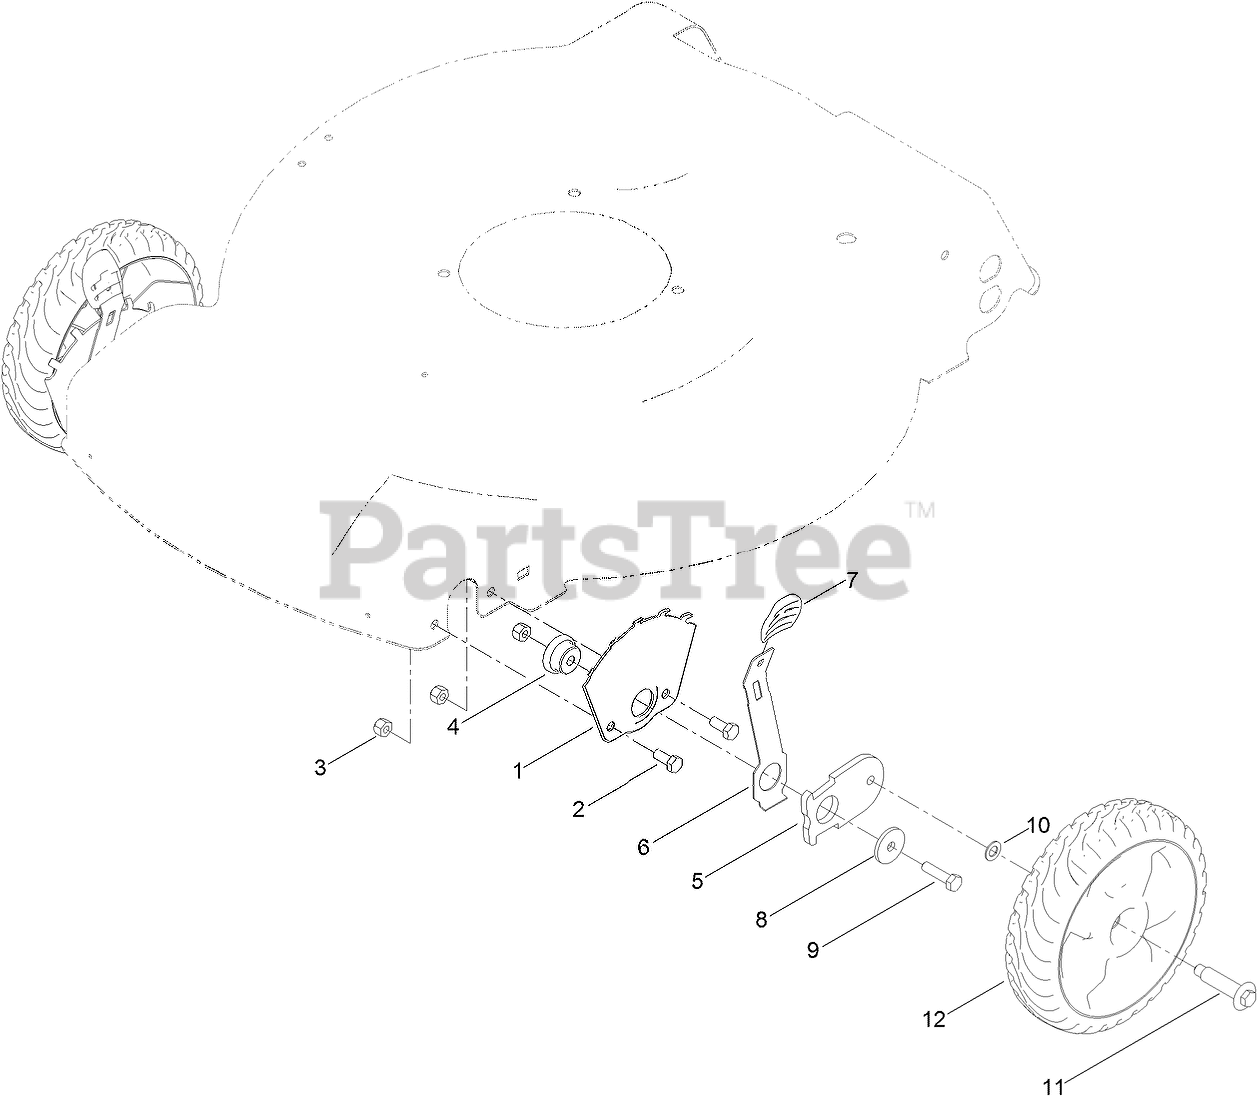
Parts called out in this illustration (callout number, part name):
1	PLATE-HOC, FRONT
2	SCREW-HH
3	NUT-LOCK, NI
4	BUSHING-MOUNT, HOC
6	ARM-SPRING
7	KNOB-LEVER, HOC
8	WASHER-FLAT
9	SCREW-HH
10	WASHER
11	BOLT-SHOULDER
12	81IN WHEEL ASM
